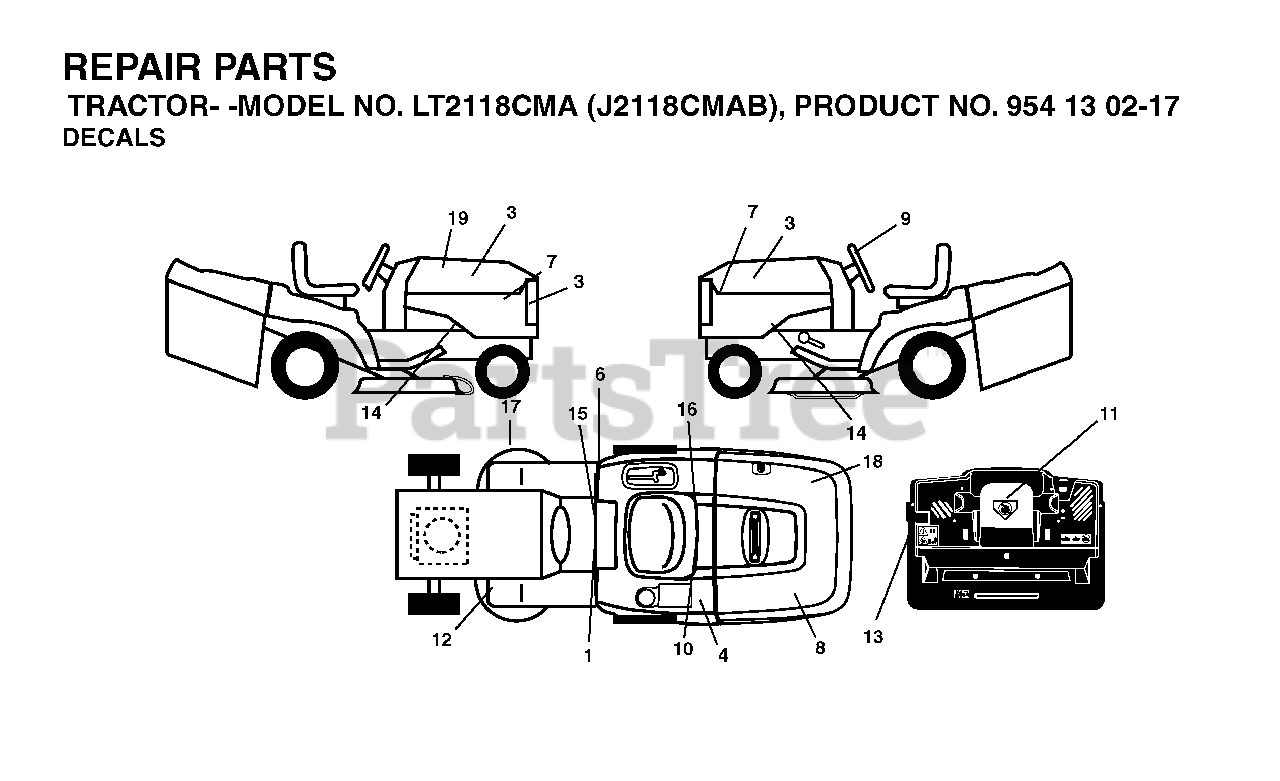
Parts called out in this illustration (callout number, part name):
1	DECAL READ OWNER'S MAN SYMS
10	DECAL BTRY SYMBOLS
11	DECAL.INTERNATIONL.CUTFINGER
15	DECAL PARK BRAKE
16	DECAL.BYPASS.FENDER.CRD.LT.YT
